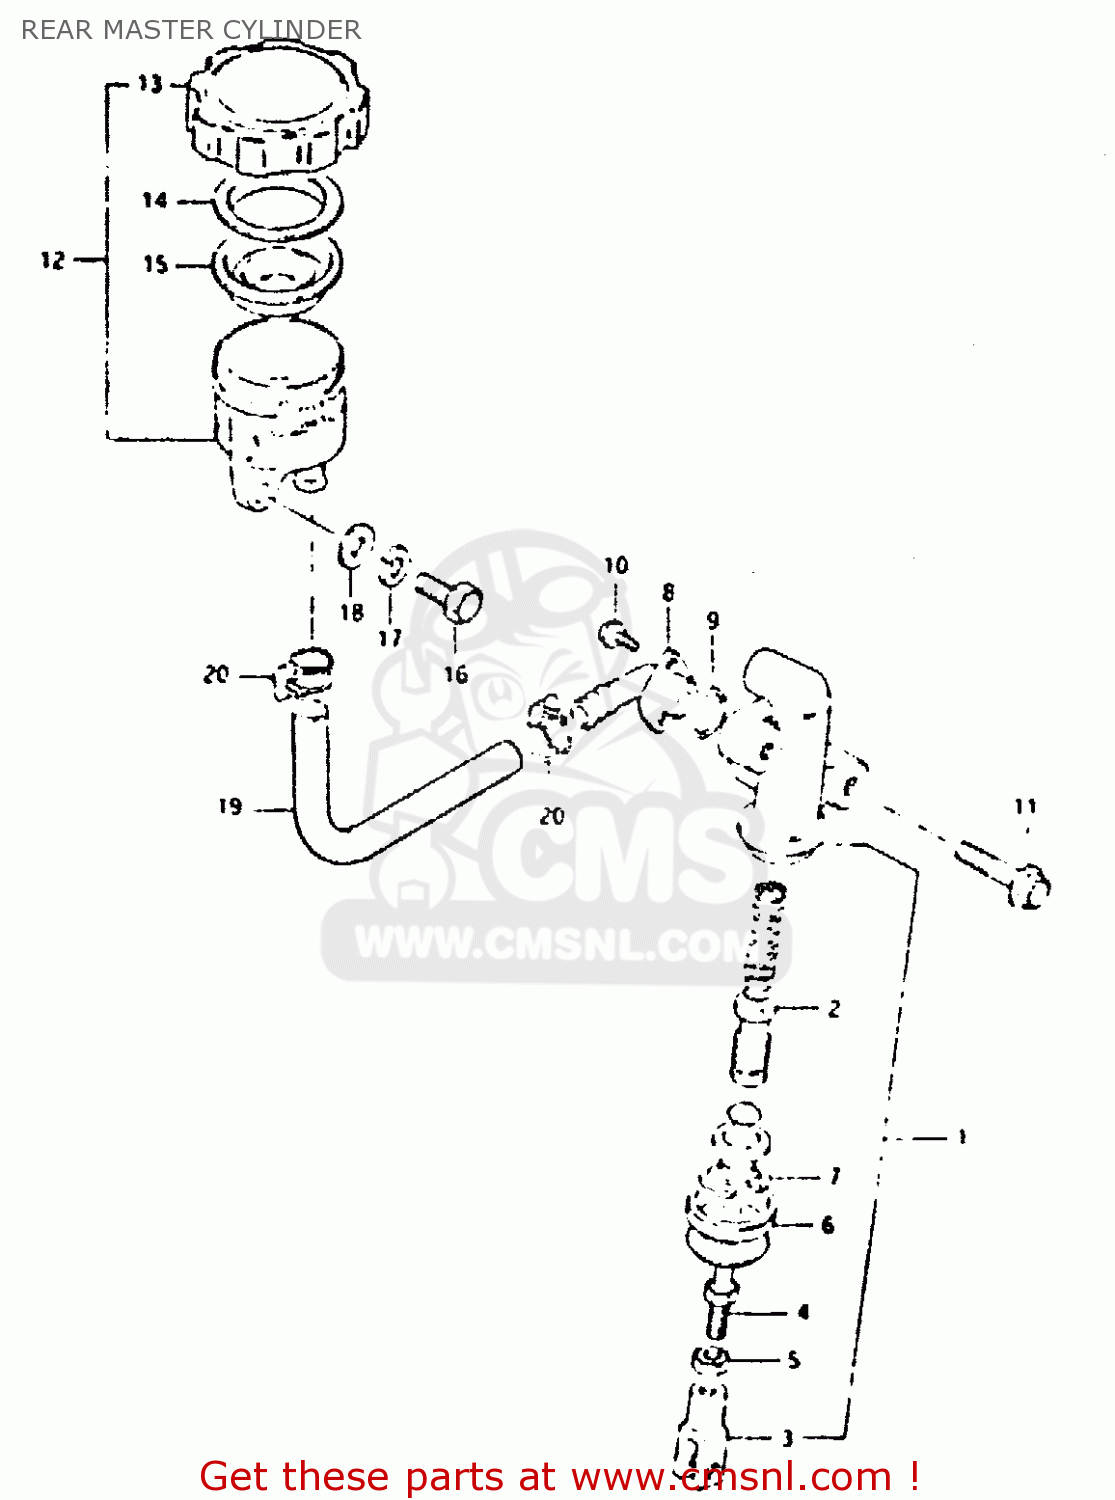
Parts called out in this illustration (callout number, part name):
1	CYLINDER ASSEMBLY,REAR MASTER
2	PISTON/CUP SET
3	YOKE
4	ROD,REAR MASTER CYLINDER
5	NUT,MASTER CYLINDER
6	BOOT
7	CIRCLIP
8	CONNECTOR,HOSE
9	O RING
10	SCREW
11	BOLT
12	TANK ASSEMBLY,RESERVOIR
13	CAP
14	PLATE,DIAPHRAGM
15	DIAPHRAGM
16	BOLT, UPPER
17	LOCK WASHER
18	WASHER
19	HOSE,RESERVOIR TANK
20	CLAMP
